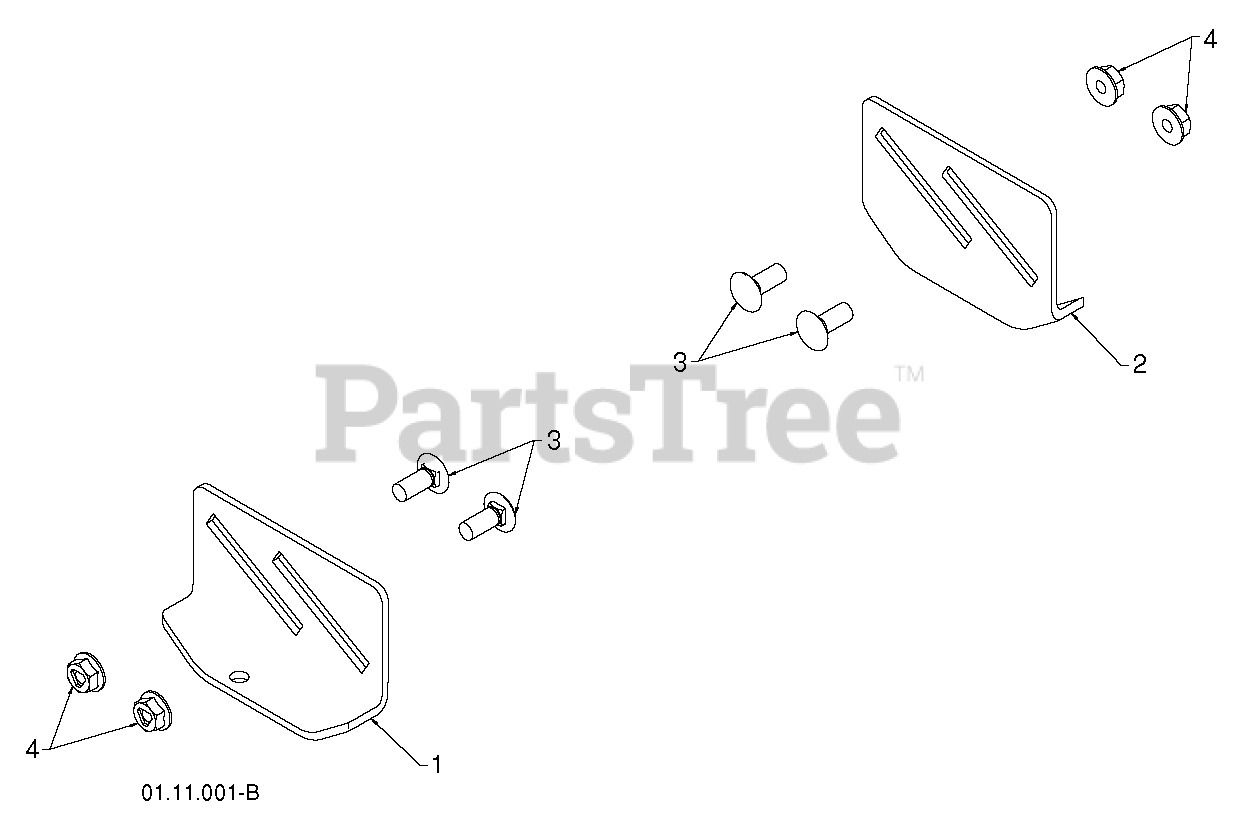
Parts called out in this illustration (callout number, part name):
1	SKID PLATE LH
2	SKID PLATE RH
4	NUTNYLOK.FLRANGE.5/16-18
